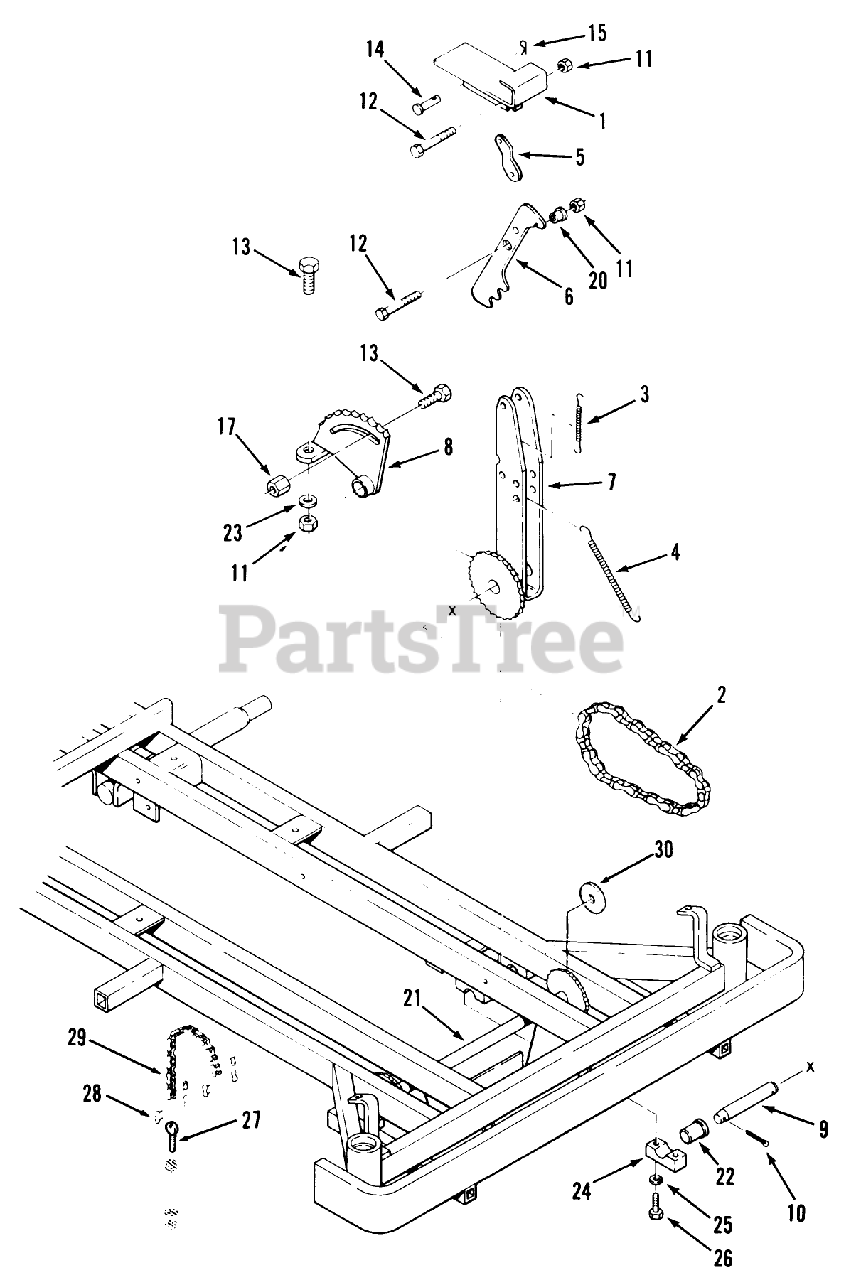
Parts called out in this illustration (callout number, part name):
1	PEDAL-FOOT 10218- B
2	CHAIN-FOOT PEDAL DR
3	SPG-NEUTRAL 20217-35
4	SPRING - EXTENSION
5	PIVOT-LINK B
6	LIFT-ARM PWL B
7	ASSY-LVR ARM 1022 B
8	HEIGHT CONTROL SP B
9	PIN-PEDAL
10	Cotter Pin
11	Nut
12	HHCS
13	Bolt
14	Pin-Clevis
15	Cotter Pin
17	HEX-STOP NUT N-140
20	BUSHING-PDL
21	ASM-Sprocket
22	BEARING-FLANGED
23	WASHER 5/16 SAE
24	Cross Shaft Clamp (Included w/frame)
25	Lockwasher 3/8 (Included w/frame)
26	Bolt 3/8-16 x 1-1/4 (Included w/frame)
27	EYE-BOLT 3/8-16X2.50
28	MASTER LINK CHAIN
29	CHAIN-DECK LIFT
30	Washer
